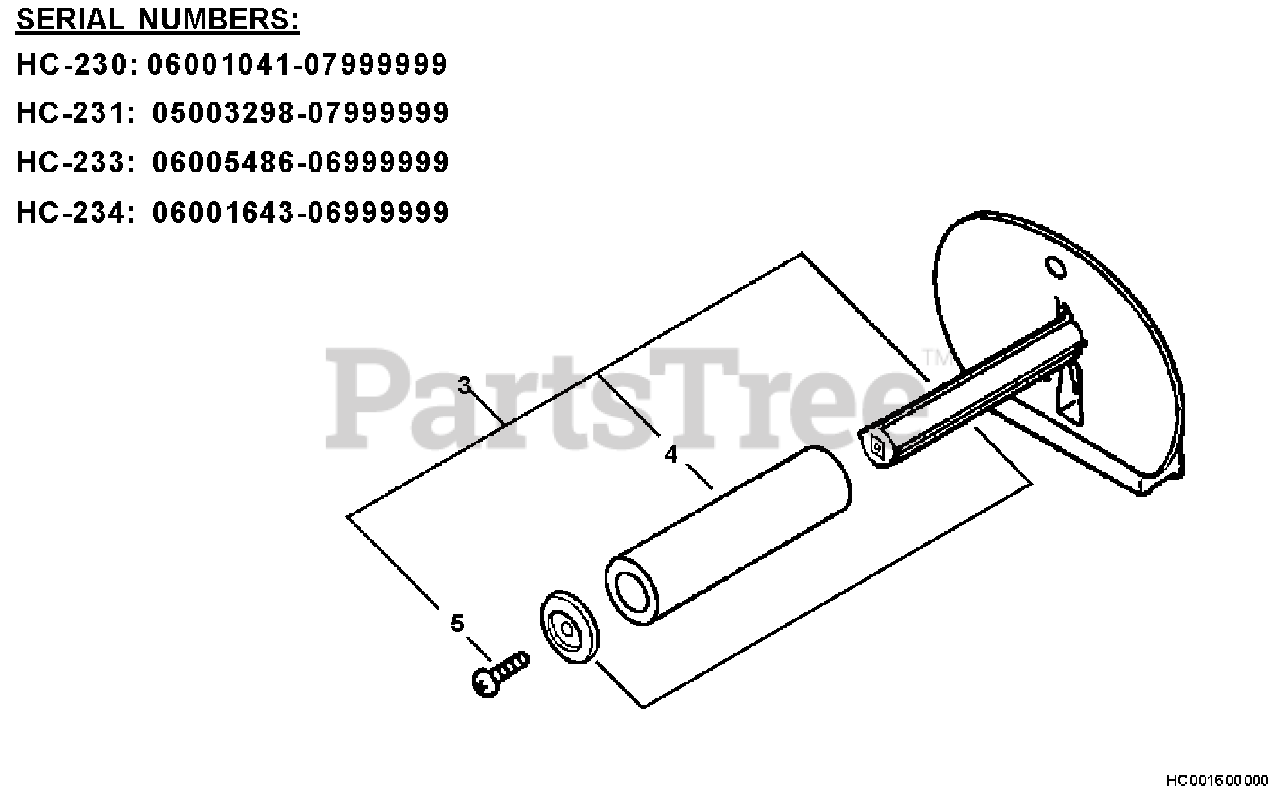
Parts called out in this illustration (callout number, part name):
3	FRONT HANDLE ASSY
4	GRIP, HANDLE
5	SCREW 5×14
